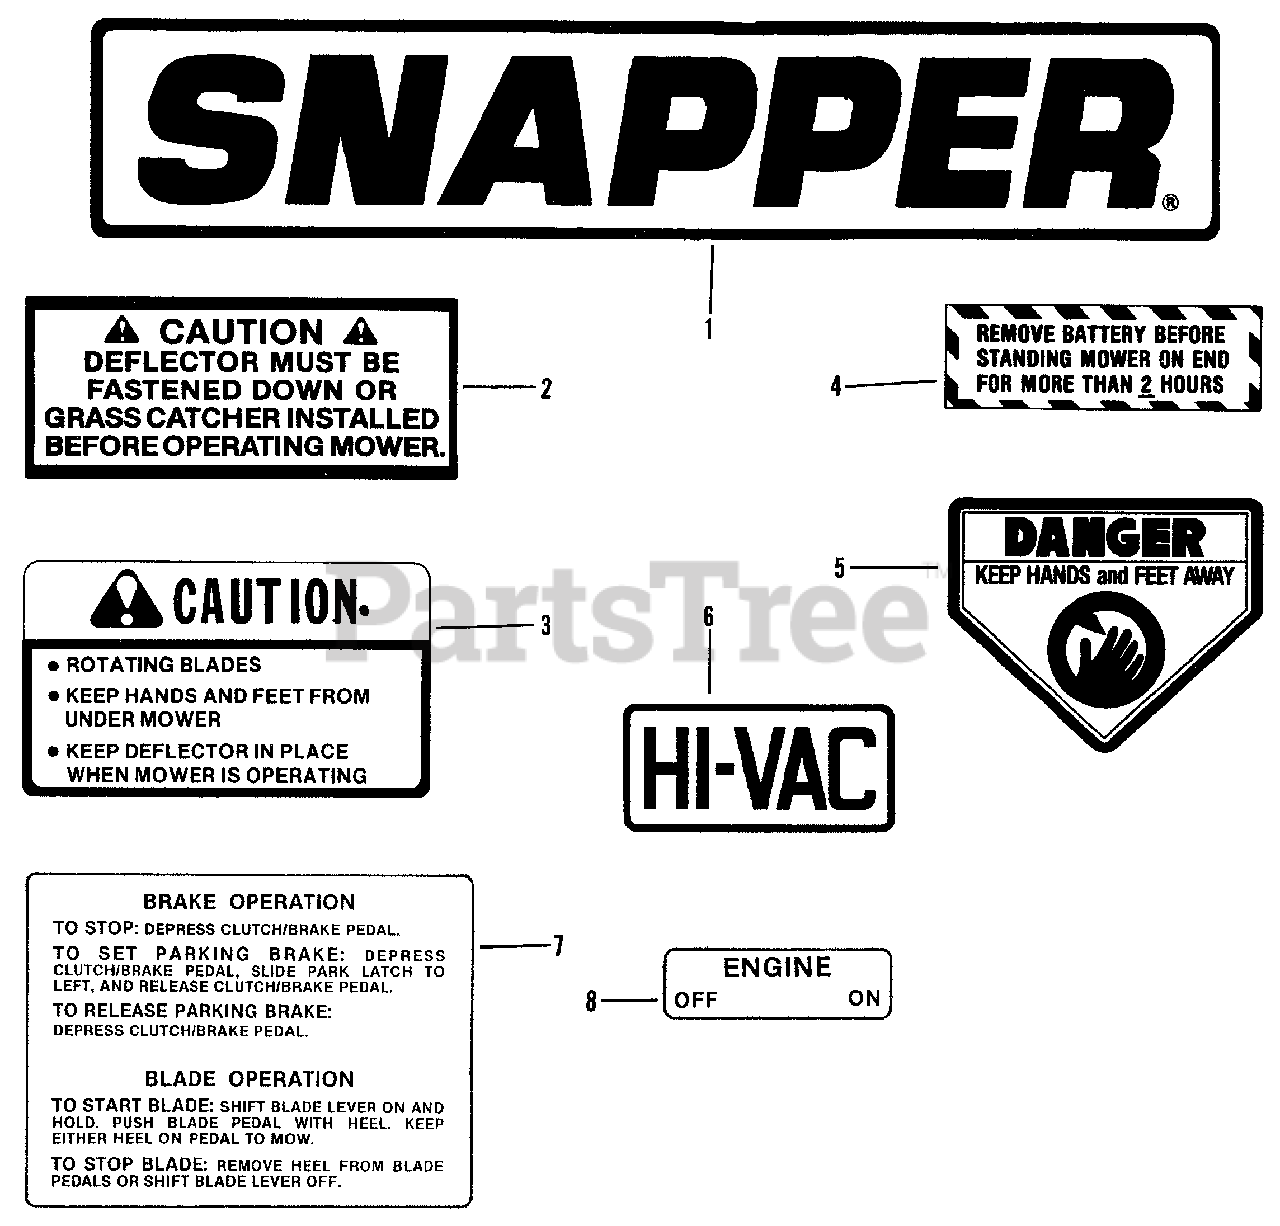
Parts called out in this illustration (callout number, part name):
1	DECAL, Snapper
2	DECAL, Caution - Deflector
3	DECAL, Caution - Rotating Blades
4	DECAL, Battery
5	DECAL, Danger (Cut Finger)
6	DECAL, Hi-Vac
7	DECAL, Blade Brake Operation
8	DECAL, Column Cap
